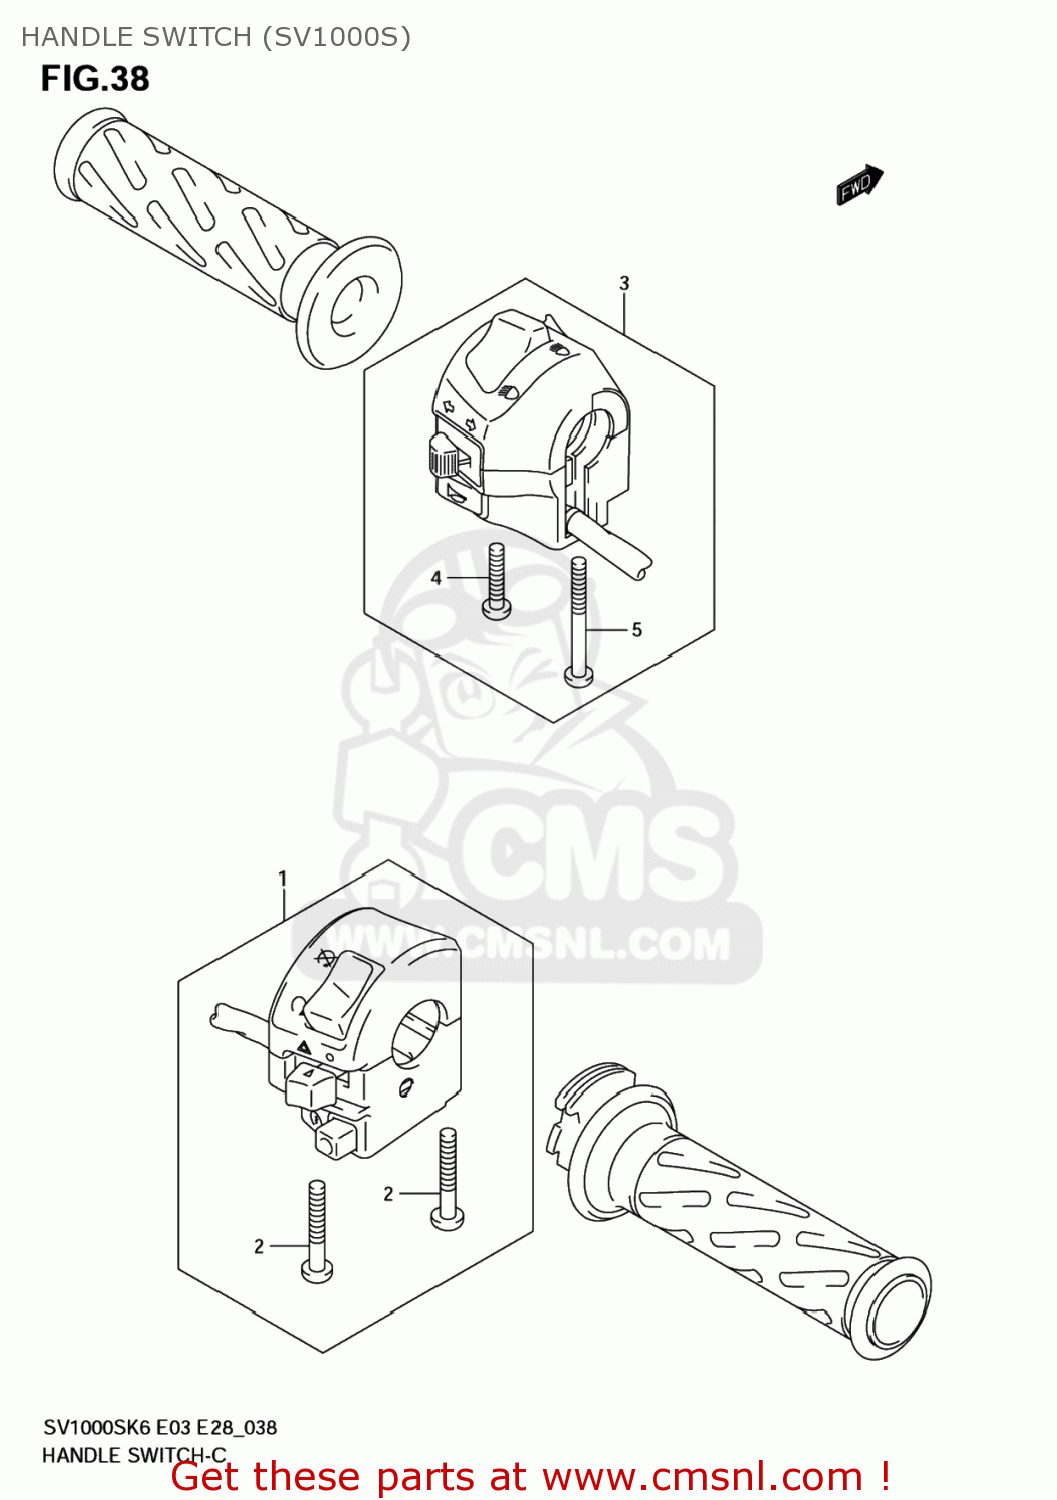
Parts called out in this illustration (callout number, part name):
1	SWITCH ASSY,HANDLE,R
2	SCREW
3	SWITCH ASSY,HANDLE,L
4	SCREW
5	SCREW
